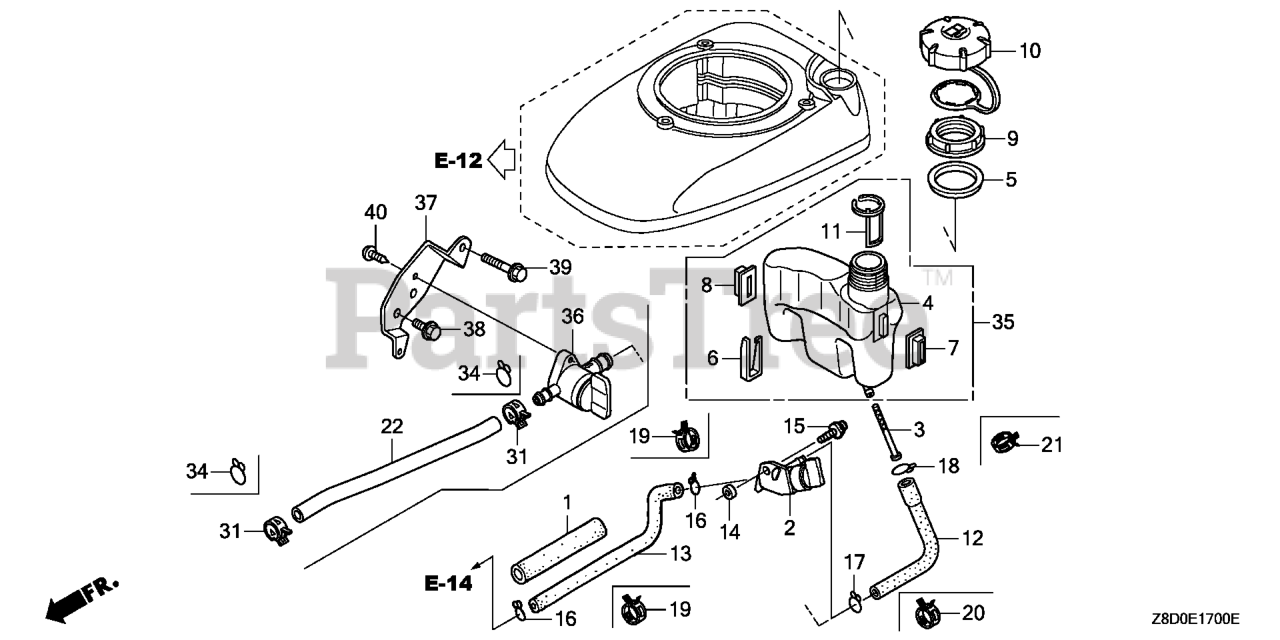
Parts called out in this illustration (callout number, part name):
3	FILTER, FUEL
4	TANK, FUEL
5	SEAL, FUEL FILLER NECK
6	CLIP, TANK MOUNTING
7	RUBBER A, TANK MOUNTING
8	RUBBER B, TANK MOUNTING
9	NUT, TANK MOUNTING
10	CAP ASSY., FUEL TANK
11	GAUGE, FUEL LEVEL
12	TUBE, FUEL (7.3X160)
17	CLIP, TUBE (B12.5)
18	CLIP, TUBE (B12.5)
22	TUBE, FUEL (4.5X110)
34	CLIP, TUBE (C9)
35	TANK KIT, FUEL
36	PETCOCK ASSY.
37	STAY, PETCOCK
38	BOLT, FLANGE (6X12) (CT200)
39	BOLT, FLANGE (6X28) (CT200) Use up to Engine SN 1530314.
40	SCREW, TAPPING (5X12) (PO)
